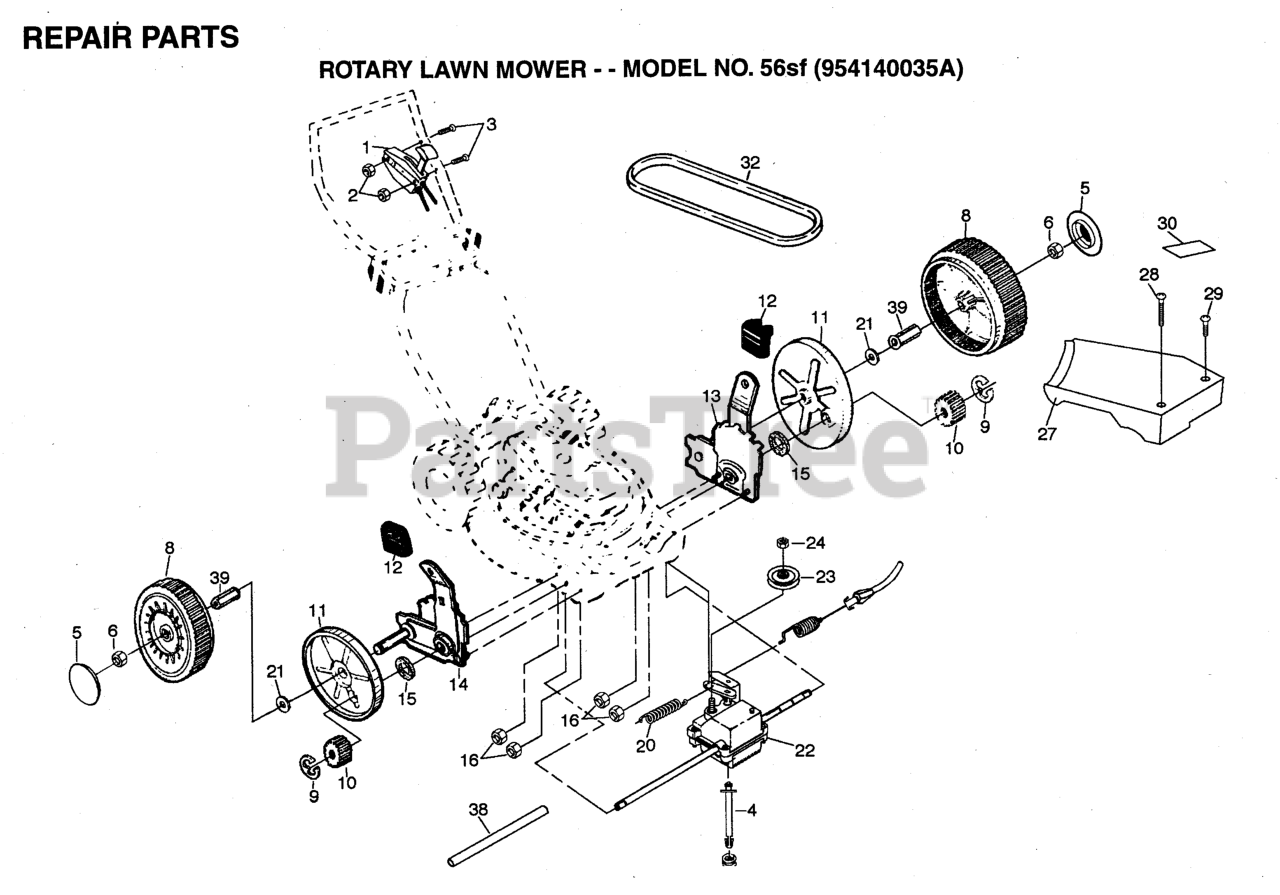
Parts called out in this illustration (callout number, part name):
1	DRIVE CONTROL
2	NUT
3	SCREW 1/4-20 X 2.12
4	SPRING RETAINER
5	HUBCAP.8".GREY
6	NUT
9	E-RING 7/16 RE
10	PINION GEAR
11	DUST SHROUD PM
12	SELECTOR KNOB
13	WHEEL ADJUSTER ASSY (LEFT)
14	WHEEL ADJUSTER KIT RH
16	NUT
18	SPRING.EXTENSION
21	WASHER FLUT
22	GEAR CASE ASMBLY
23	PULLEY
24	FLANGED LOCKNUT 3/8-16 ZINC
27	DRIVE COVER-GRAY
29	SCREW.SLOT.TORX.
32	BELT THERM .32
38	DRV SHAFT TUBE PM
